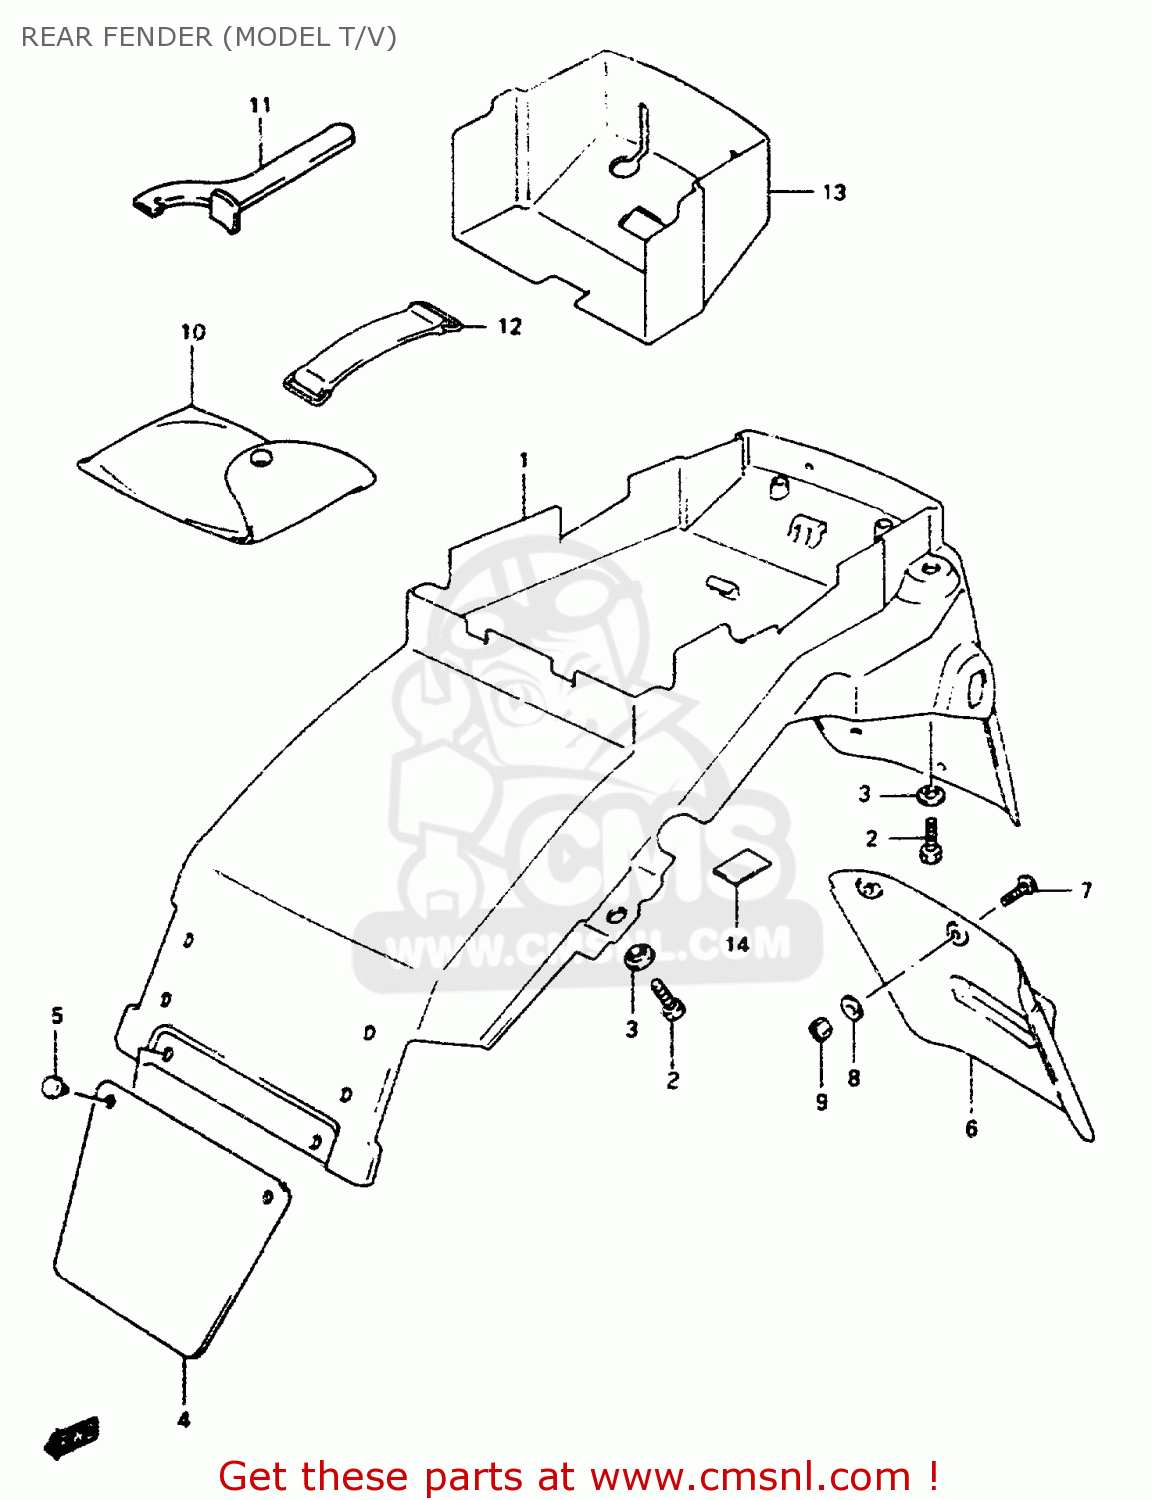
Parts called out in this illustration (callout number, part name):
1	FENDER,RR
2	BOLT
3	WASHER
4	GUARD,RR FENDER MUD
5	CLIP,MUDGUARD
6	EXTENSION,RR FENDER
7	SCREW
8	WASHER
9	NUT
10	TOOL ASSY
11	CLAMP
12	BAND
13	CLAMP
14	TAPE,RR FENDER
15	TAPE,RR FENDER
